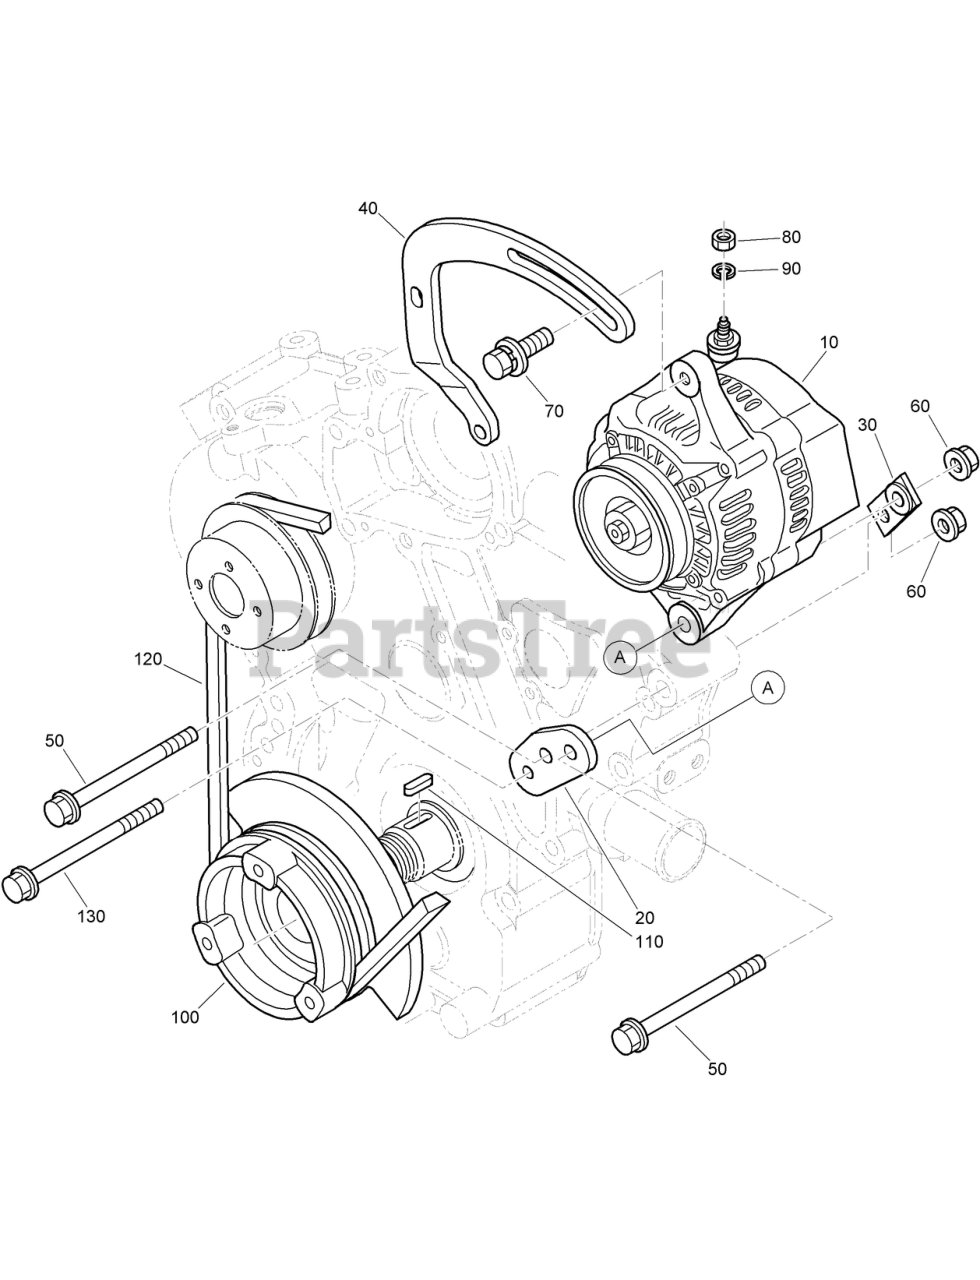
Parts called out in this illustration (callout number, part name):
10	ALTERNATOR ASM
20	SUPPORT-ALTERNATOR
30	STAY-ALTERNATOR
40	STAY-DYNAMO
50	BOLT-FLANGE
60	NUT-FLANGE
90	WASHER-SPRING
100	PULLEY-DRIVE, FAN
110	KEY-FEATHER
120	BELT-FAN
130	BOLT-FLANGE
